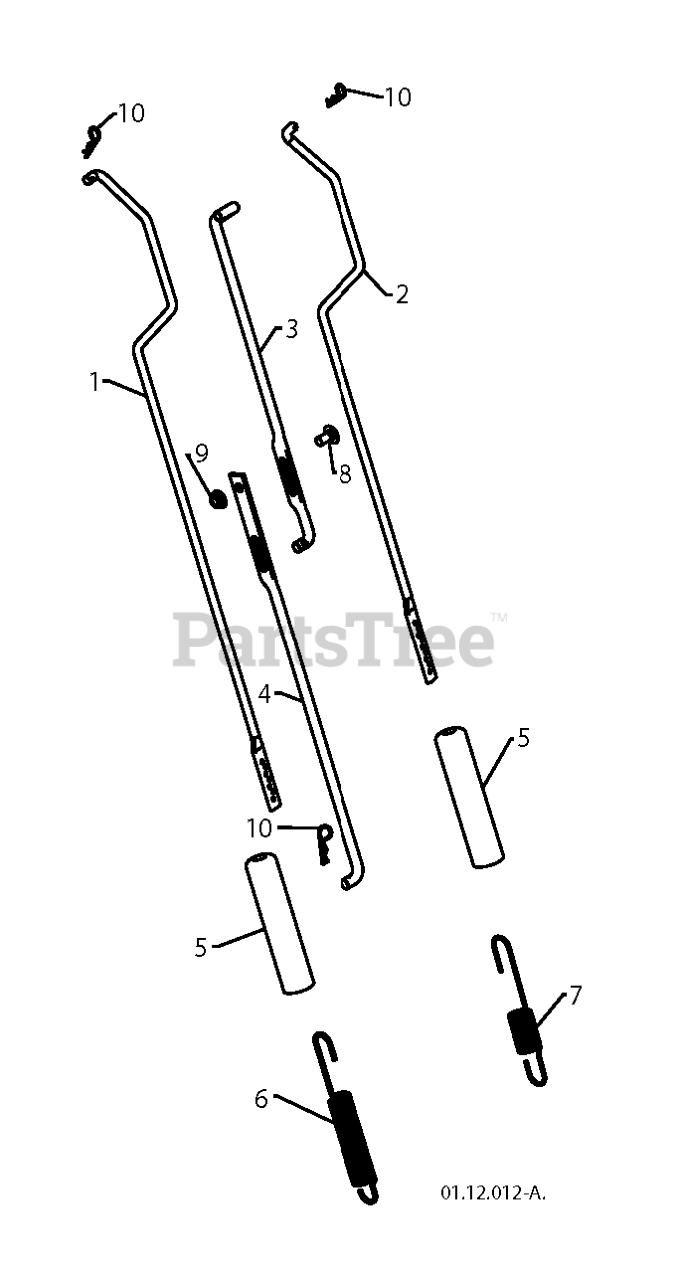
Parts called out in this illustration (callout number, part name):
1	ROD.ASM.IMPELLER.HYD
2	ROD.ASM.TRACTION.HYD.CLUTCH
3	ROD.SHIFTER.TOP.HYD.SNOW
4	ROD, LOWER, SPEED CONTROL
5	SLEEVE, SPRING
6	SLEEVE, SPRING
7	SPRING, AUGER CONTROL
8	SPRING, TRACTION DRIVE
9	BOLT
10	NUT.FLANGE.5/16
